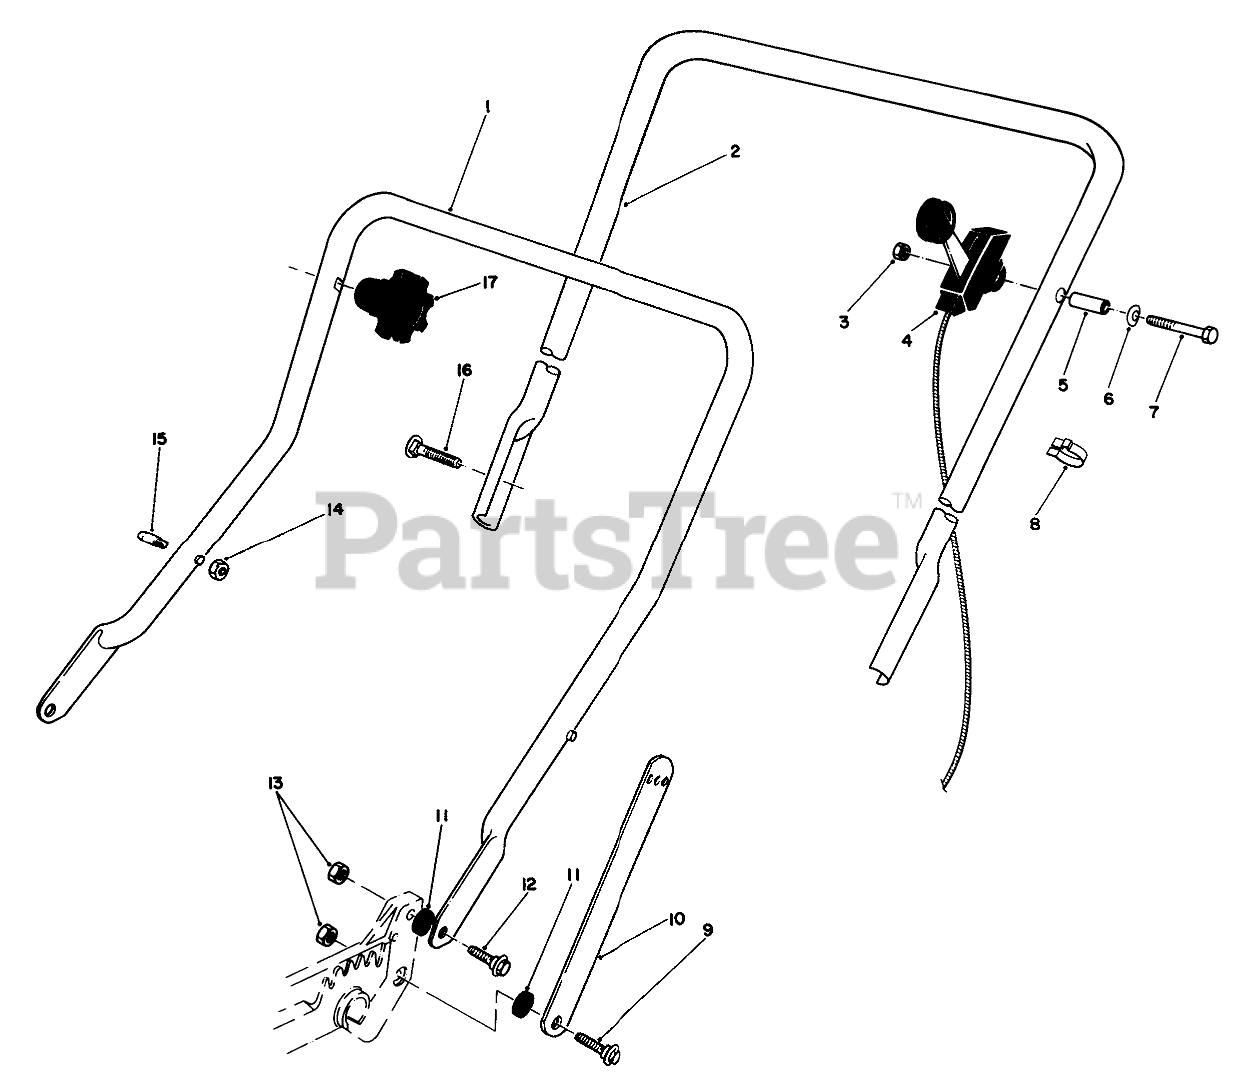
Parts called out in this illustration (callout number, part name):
1	Handle-Lower
2	UPPER HANDLE
3	NUT-LOCK, NI
4	SERVICE THROTTLE CONTRO
5	Spacer
6	WASHER
7	SCREW-HH
8	BOWDEN CLIP
9	SCREW-SHOULDER
10	Handle Latch
11	SPACER
12	SCREW-SHOULDER
13	NUT-LOCK, NI
14	NUT-LOCK, NI
15	HANDLE PIN
16	5/16-18 X 2 HNDLE SCREW
